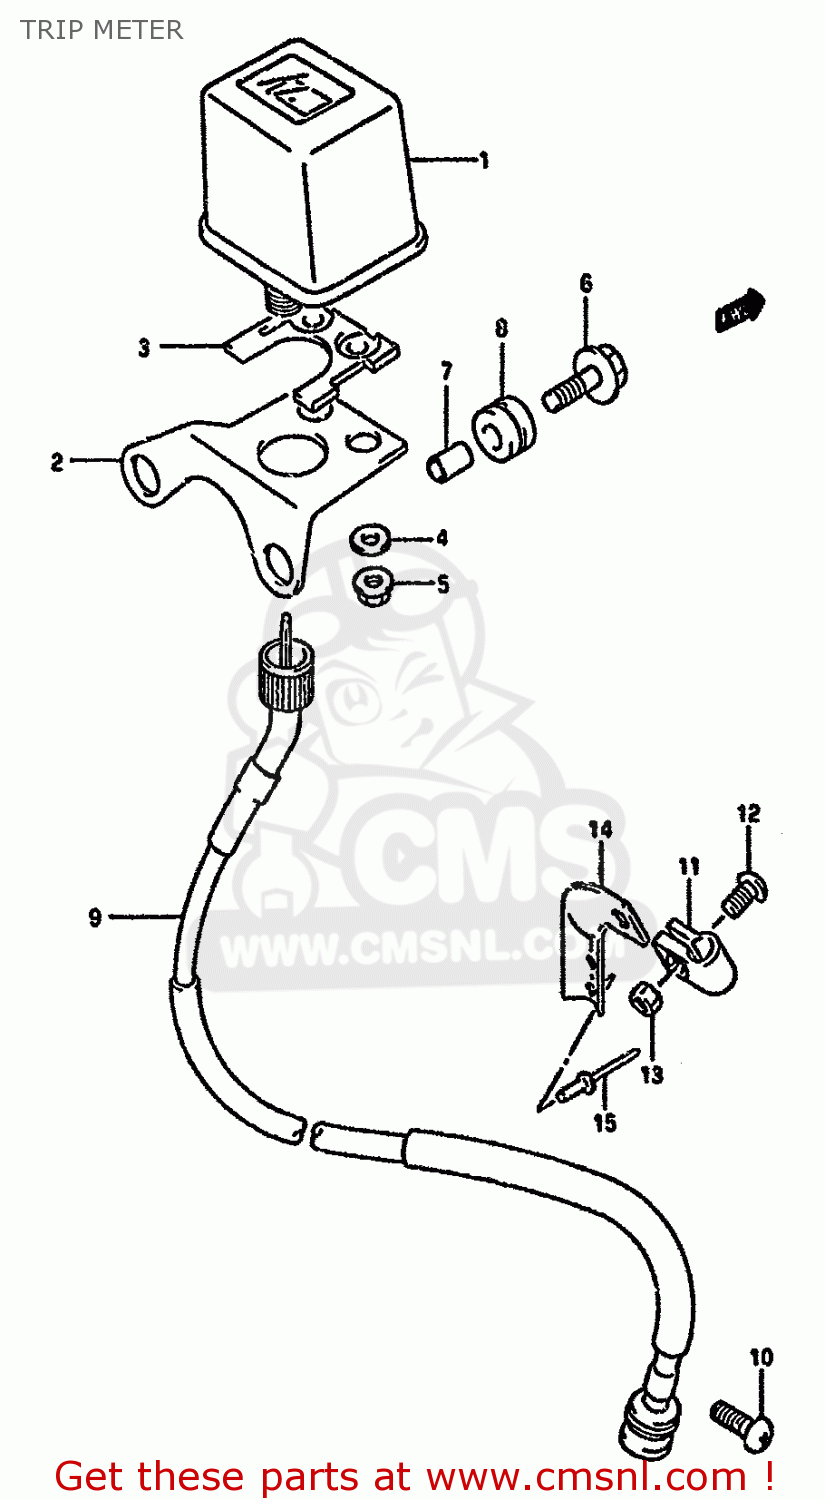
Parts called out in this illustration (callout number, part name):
1	TRIP METER
2	BRACKET
3	CUSHION
4	WASHER,METER
5	NUT
6	BOLT(6X25)
7	SPACER (6.1X8X9.5)
8	CUSHION
9	CABLE ASSY,TRIP METER
10	SCREW
11	CLAMP,FR BRAKE CABLE
12	SCREW
13	NUT
14	BRACKET,METER CABLE GUIDE
15	RIVET
